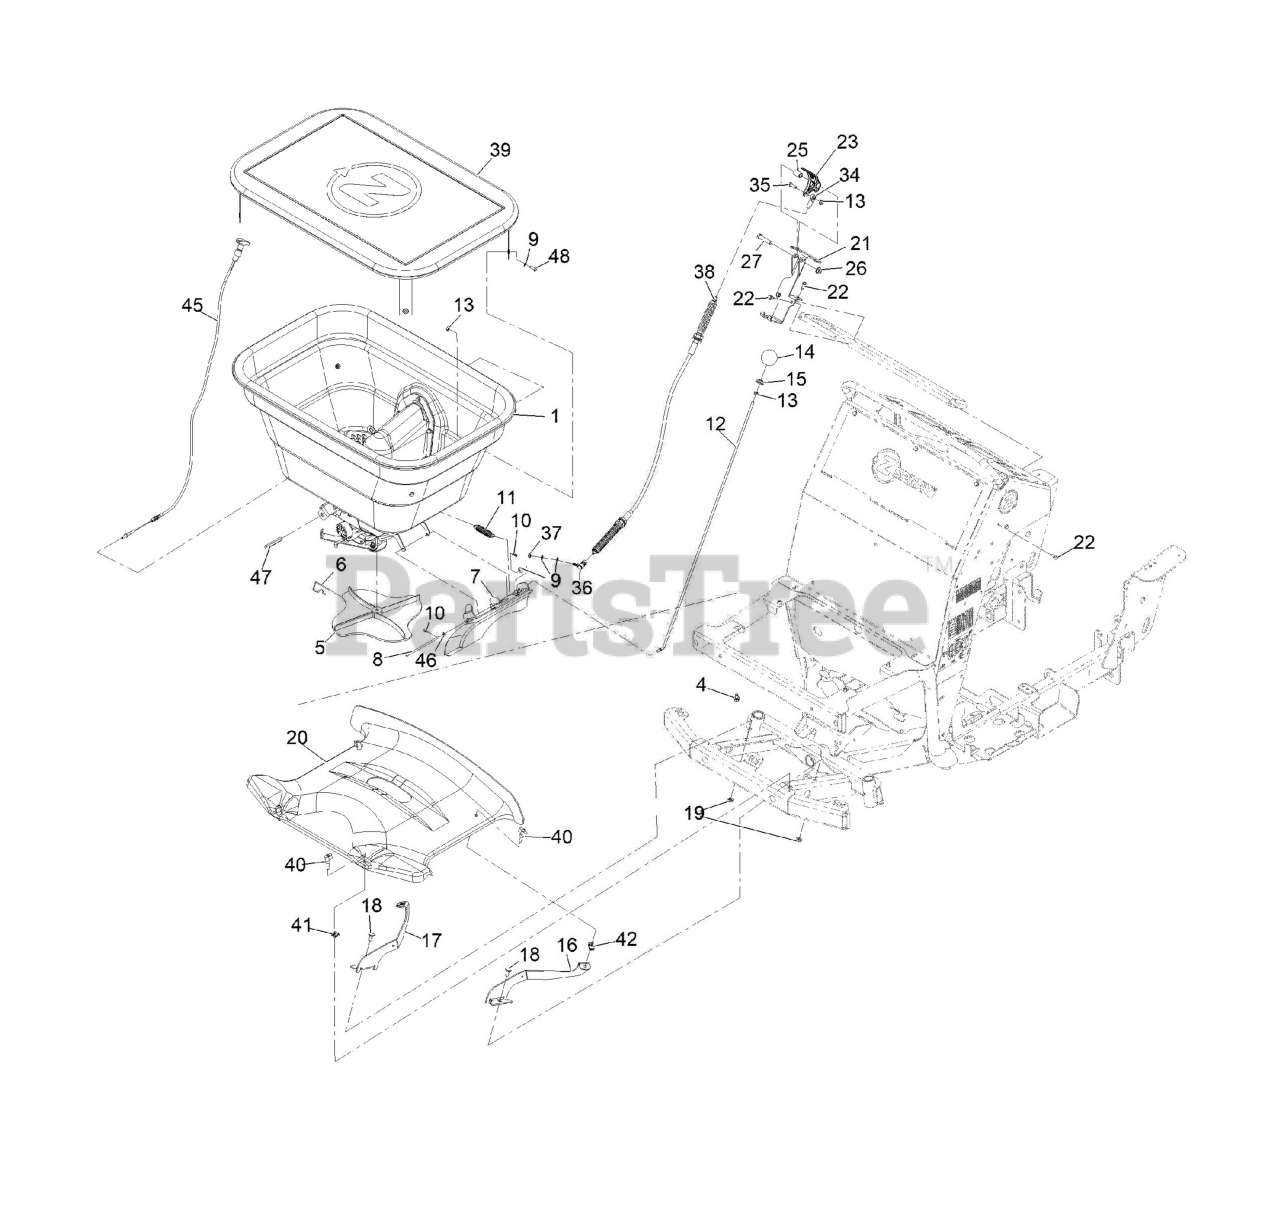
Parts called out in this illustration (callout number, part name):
1	Spreader Hopper ASM
4	SCREW-HHF
5	Spinner-Spreader
6	Clip-Spinner
7	Side Deflector ASM
8	PIN-DEFLECTOR SS
9	WASHER-FLAT
10	PIN-COTTER, HAIR
11	SPRING-EXTENSION
12	ROD-CONTROL, DEFLECTOR
14	KNOB-RATE, FLOW
15	GROMMET
16	BRACKET-COVER, FRONT (LH)
17	BRACKET-COVER, FRONT (RH)
18	SCREW-CARR
20	COVER-FRONT, SPREADER/SPR
21	Mount-Handle, Fert Gate
22	SCREW-HWH
23	Lever-Spread, Wide
27	SCREW-HH
34	ROD END-BALL JOINT
35	SCREW-HH
36	BALL-JOINT
37	NUT-HEX, NI
39	Cover-Hopper, Clear Vinyl Window
41	NUT-RETAINER, U STYLE
42	NUT-RETAINER
45	CABLE-CONTROL, TURN LOCK
46	WASHER-FLAT
47	POST-HEX, DIFFUSER GUIDE
48	SCREW-HH
